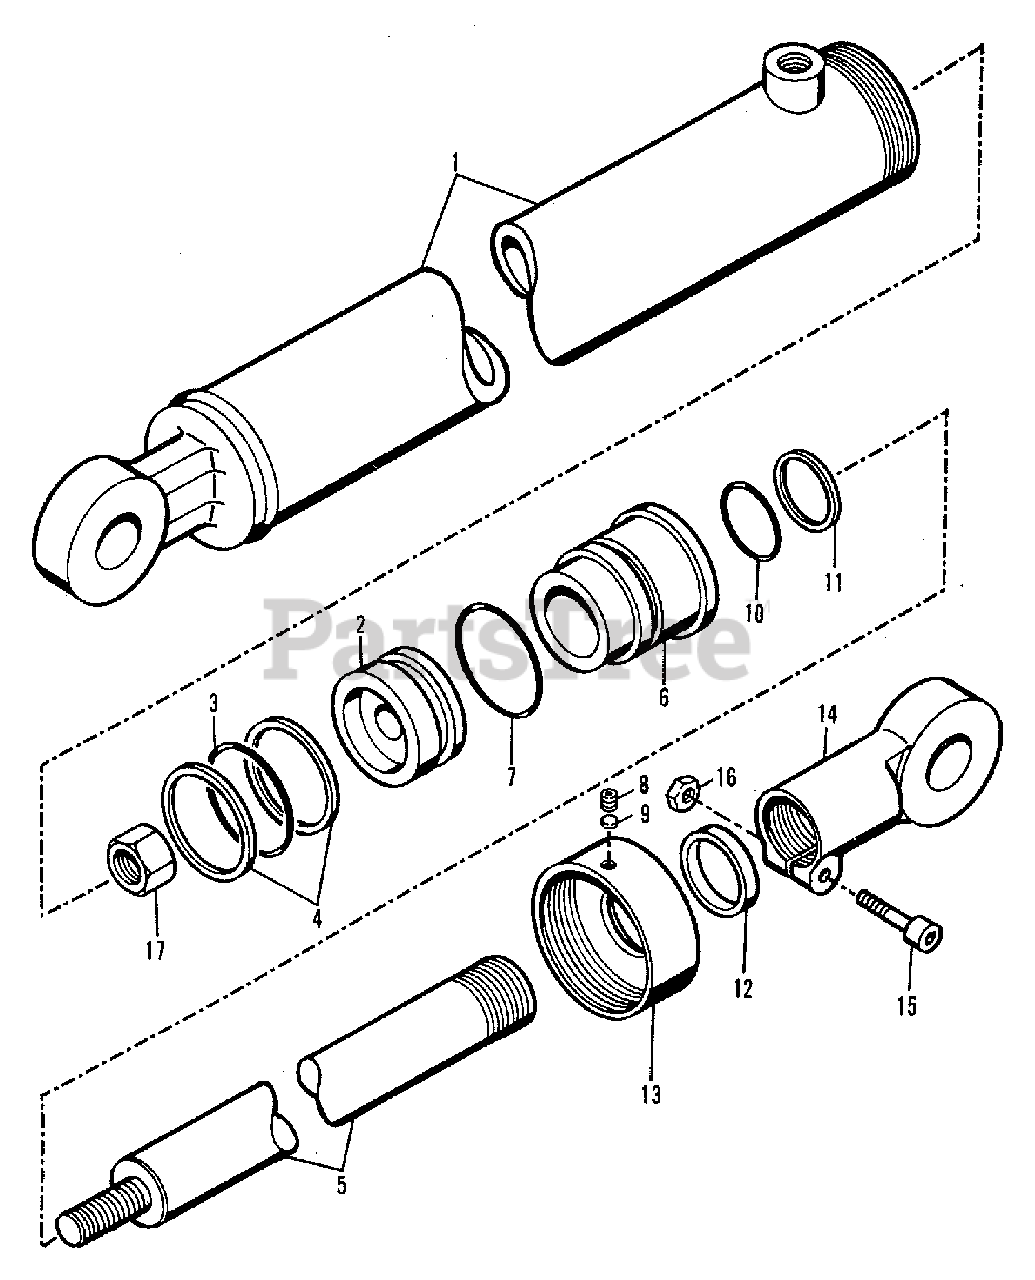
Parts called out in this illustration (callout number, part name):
1	TUBE ASSEMBLY
3	O-RING, Piston
4	WASHER, Backup, Large
5	ROD, Piston
7	O-RING, Rod Guide, Large
8	SETSCREW, Tube Cap
9	PLUG, Nylon
10	O-RING, Rod Guide, Small
11	WASHER, Backup, Small
12	WIPER, Rod
13	CAP, Tube & Rod
14	EYE, Piston Rod
15	CAPSCREW, Rod Eye
16	NUT, Capscrew (Rod Eye)
17	NUT, Piston Rod
